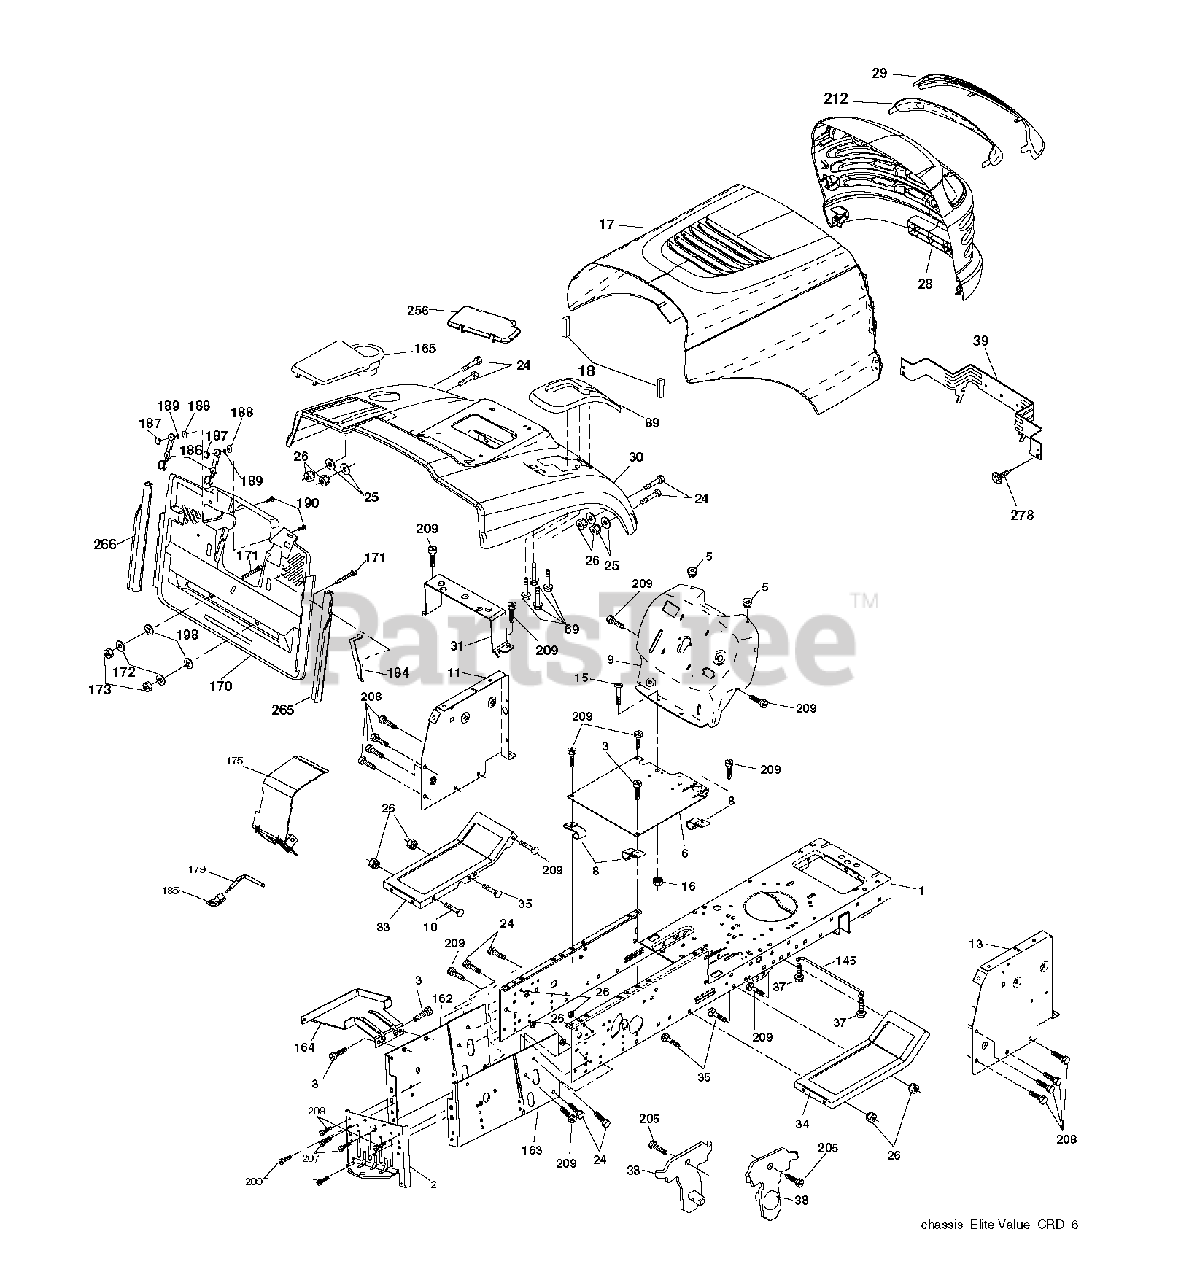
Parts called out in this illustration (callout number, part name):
1	CHASSIS
3	SCREW 3/8-16X3/4
5	BUMPER.RUBBER.HOOD
8	CLIP,INSULATOR
10	BOLT D
11	PANEL.DASH.LH.LTX
13	PANEL DASH RH
16	NUT
18	BUMPER.HOOD.LARGE.1.75"
25	WASHER
26	NUT
31	BRACKET SUPPORT FENDER
39	BRACKET PIVOT
69	SCREW.HI-LO.CONSOLE
145	ROD.PIVOT.HOOD
164	SUPPORT
171	BOLT
172	WASHER
186	LATCH ASSY
187	WELDNUT
189	LOCKWASHER
207	SCREW, 5/16-18 X 1/2
208	SCREW 3/8-16X1/2
209	SCREW, 3/8-16X3/4
278	SCREW.#10 X 0.750.BOS THREAD
